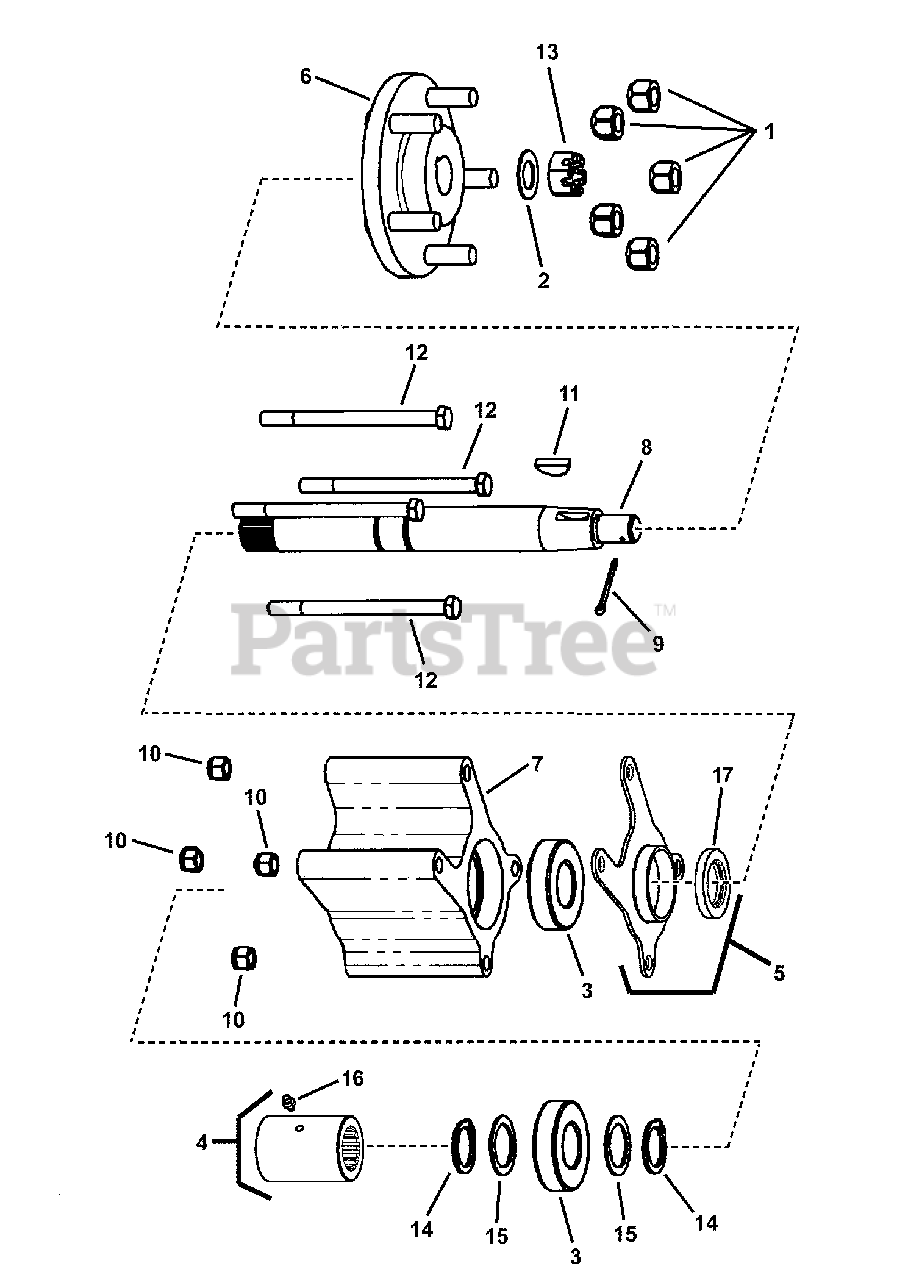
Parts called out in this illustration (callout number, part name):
1	LUG NUT, 1/2-20 Hex
1	WASHER, 5/16" SAE
2	WASHER, .77 x 1.5 x .06 Flat
2	BOLT, 5/16-18 X 1 GD5 YZ
3	BEARING, 30mm x 62mm
3	NUT, 5/16-18 HEX NYLOCK FLANGE
4	ASSEMBLY, Coupling (incl. Ref. No. 16)
4	NUT, 5/16-18 HEX SERRATED FLANGE (SMALL)
5	BOLT, 5/16-18 X 1-1/4, CARRIAGE YZ
6	SPACER, .25 X .37 X .25
7	BOLT, 1/4-20 X 3/4", CARRIAGE
8	NUT, 1/4-20 HEX NYLOCK FLANGE
9	WASHER, .34 X 1.25 X 10 GA
10	NUT, 3/8-16 HEX NYLOCK FLANGE
11	PLATE, SIO FLOOR MOUNT - RED
12	SEAT, NO ARM REST
13	SEAT PLATE, STOP - RED
